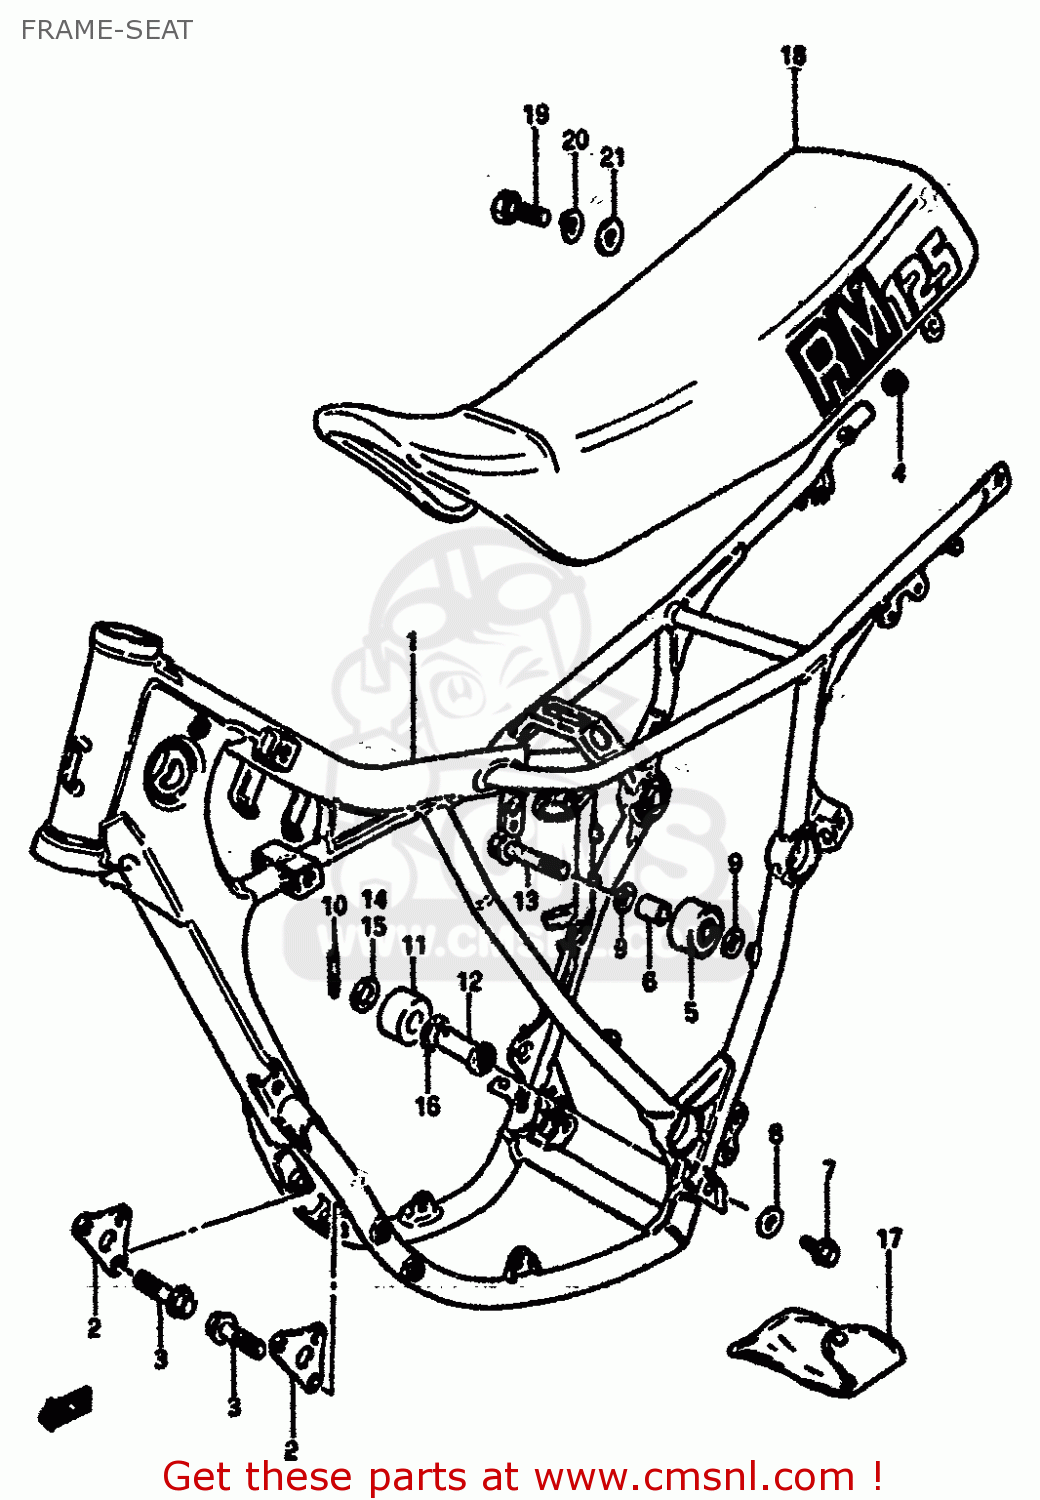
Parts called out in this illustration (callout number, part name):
1	FRAME
2	PLATE,ENGINE MOUNTING
3	BOLT(8X36)
4	CAP(OD:19)
5	ROLLER,CHAIN
6	SPACER(8.6X12X25.5)
7	BOLT
8	WASHER
9	WASHER
10	PIN 25X20
11	ROLLER,CHAIN LENGTH CONTROL
12	BOSS,CHAIN LENGTH ROLLER
13	BOLT(8X45)
14	WASHER
15	WASHER
16	WASHER
17	TOOL SET
18	SEAT ASSEMBLY
19	BOLT
20	LOCK WASHER
21	WASHER
